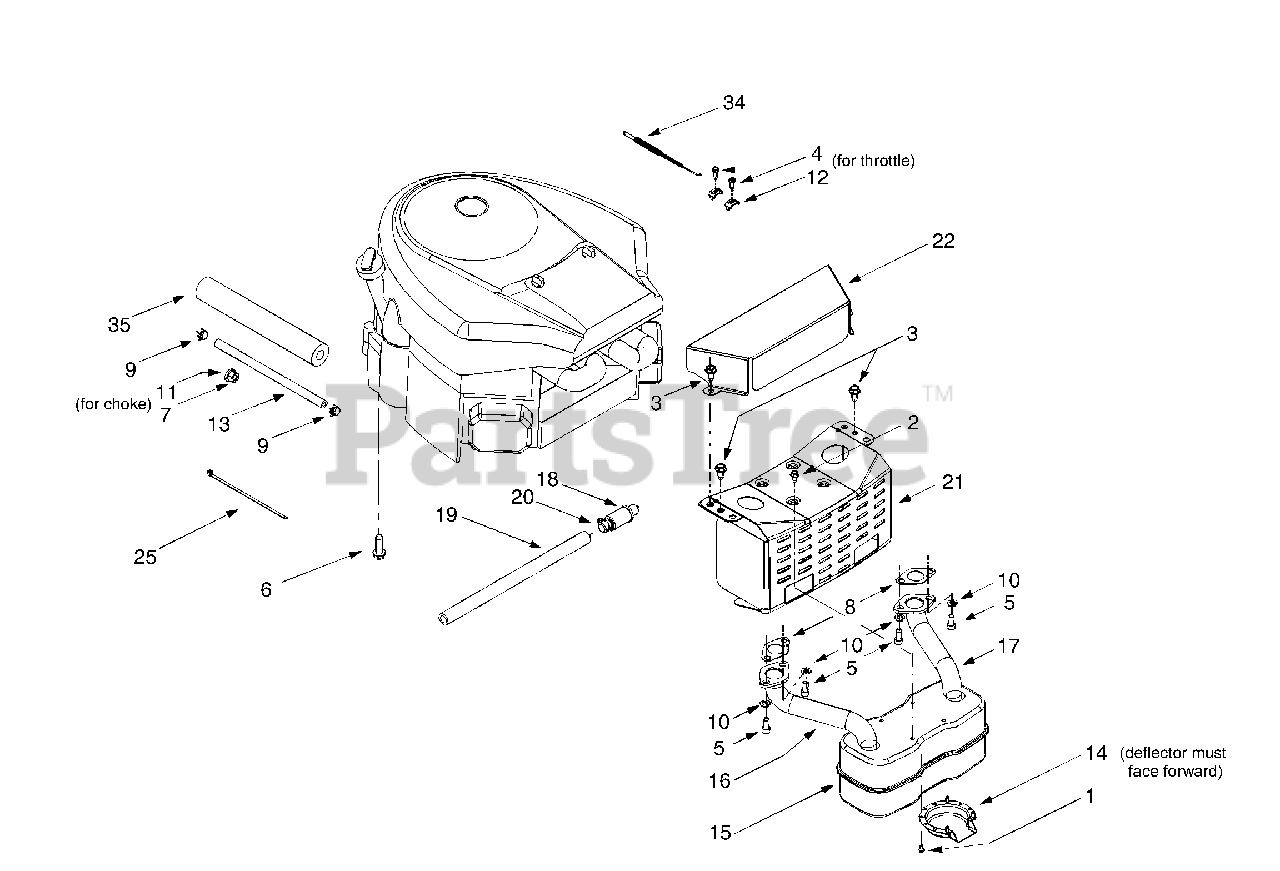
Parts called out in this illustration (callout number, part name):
1	Retainer Hook
2	Spindle Assembly, 5.75 Dia.
5	Deck Brake Assembly, 42-inch Decks
6	Hex Cap Screw, 3/8-16 x 1.5
7	Hex Cap Screw, 5/16-18 x 1.25
8	Self-tapping Screw, 5/16-18 x .625
9	Hex Cap Screw, 1/4-20 x .62
10	Self-tapping Screw, 5/16-18 x 1.25
11	Hex Cap Screw, 1/4-20 x 2.5
12	Self-tapping Screw, 5/16-18 x .75
13	Ferrule, 5/16-18
14	Hex Flange Nut, 5/8-18
15	Flange Lock Nut, 3/8-16
16	Flange Lock Nut, 5/16-18
17	Hex Nut, 1/4-20
19	Hex Flange Lock Nut, 1/4-20
20	Internal Cotter Pin, .072 x 1.12
21	Cotter Pin, 3/32 x 1.0
22	Deck Adjustment Gear
25	Side Discharge Chute Assembly
34	Flat Washer, .320 x 3.0 x .125
35	Shoulder Screw, .498 x 1.53
